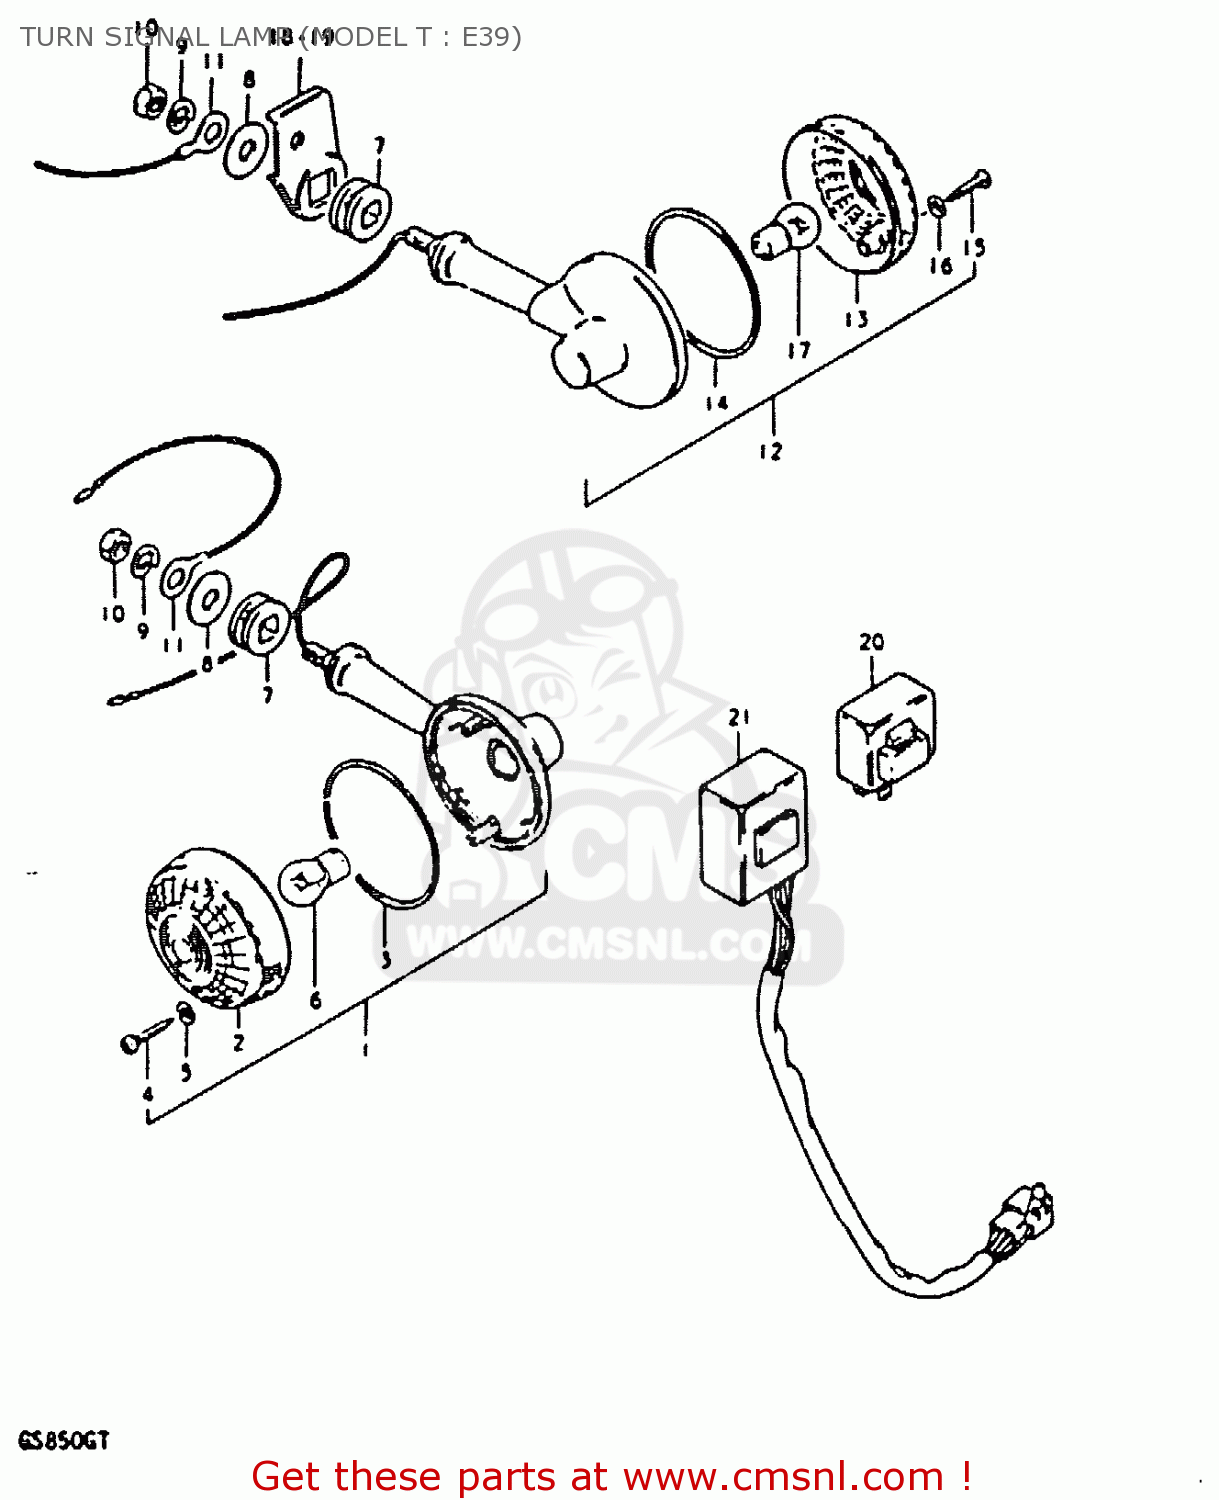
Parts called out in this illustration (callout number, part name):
1	LAMP, REAR TURN SIGNAL
2	LENS
3	GASKET (NAS)
4	SCREW (4X30)
5	GASKET (NAS)
6	BULB(12V21W)
7	CUSHION
8	WASHER (10.5X30X2.3)
9	LOCK WASHER
10	NUT
11	LEAD WIRE,EARTH
12	LAMP, REAR TURN SIGNAL
13	LENS
14	GASKET (NAS)
15	SCREW (4X30)
16	GASKET (NAS)
17	BULB(12V21W)
18	BRACKET,RR TURNSIGNAL LAMP,R
19	BRACKET,RR TURNSIGNAL LAMP,L
20	RELAY ASSY,TURNSIGNAL
21	UNIT,TURN SIGNAL CONTROL
